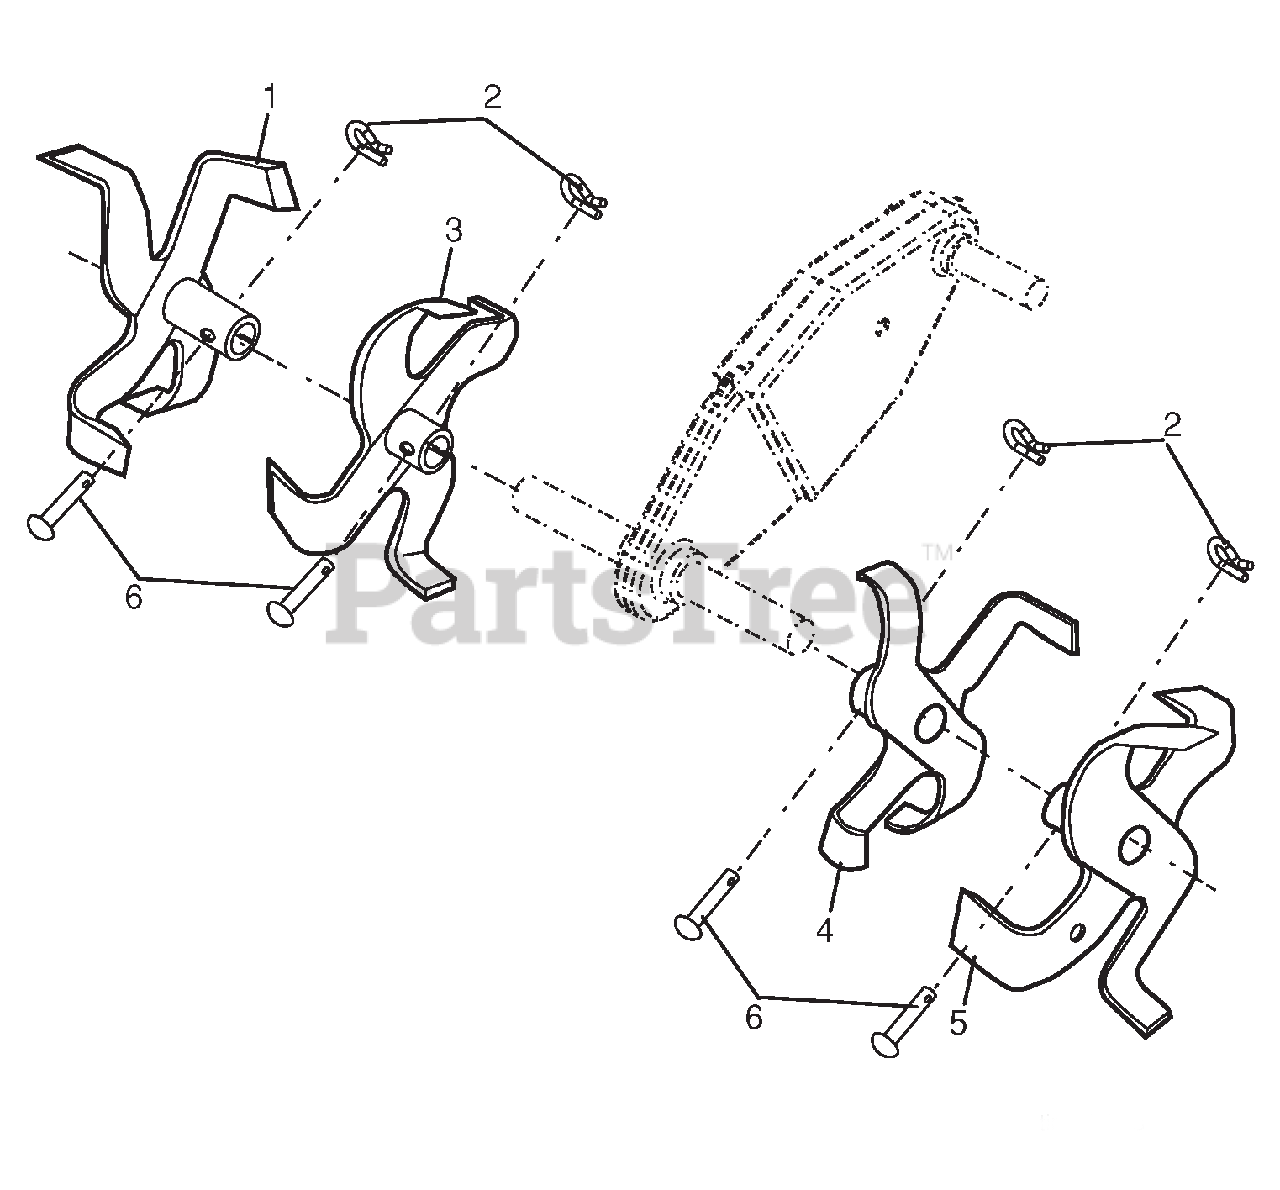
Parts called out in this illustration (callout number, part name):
1	Tine, Outer, R.H.
2	Retainer, Spring
3	Tine, Inner, R.H.
4	Tine, Inner, L.H.
5	Tine, Outer, L.H.
6	Pin, Clevis
